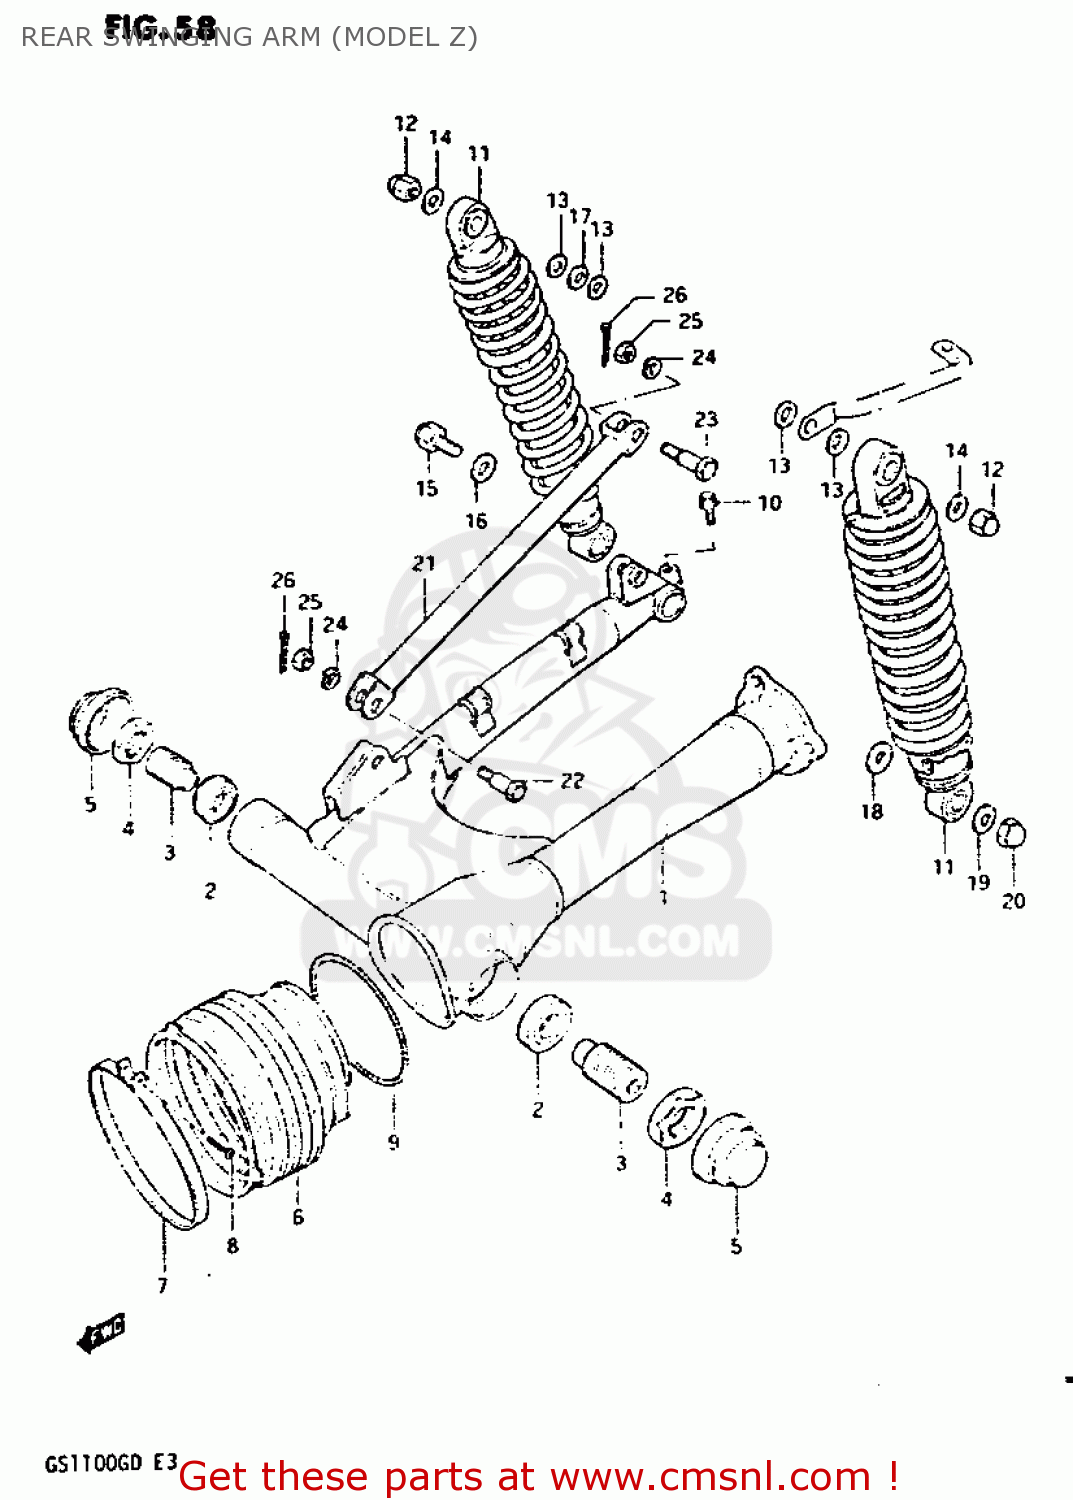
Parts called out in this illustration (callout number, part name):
1	SWING ARM SET,REAR (B
2	BEARING(17X40X13.25)
3	BOLT,REAR SWING ARM PIVOT
4	NUT
5	CAP,REAR SWING ARM PIVOT
6	BOOT,PROPELLER SHAFT
7	CLAMP
8	SCREW 4X25
9	SPRING,PROPELLER SHAFT
10	BOLT
11	ABSORBER ASSEMBLY,REAR SHOCK
12	NUT
13	WASHER
14	WASHER
15	BOLT 12X33
16	WASHER (12.5X24X1.6)
17	WASHER (12.5X24X3.2)
18	WASHER
19	WASHER
20	NUT
21	TORQUE LINK,REAR
22	BOLT
23	BOLT(10X39)
24	WASHER
25	NUT
26	PIN 20X20
